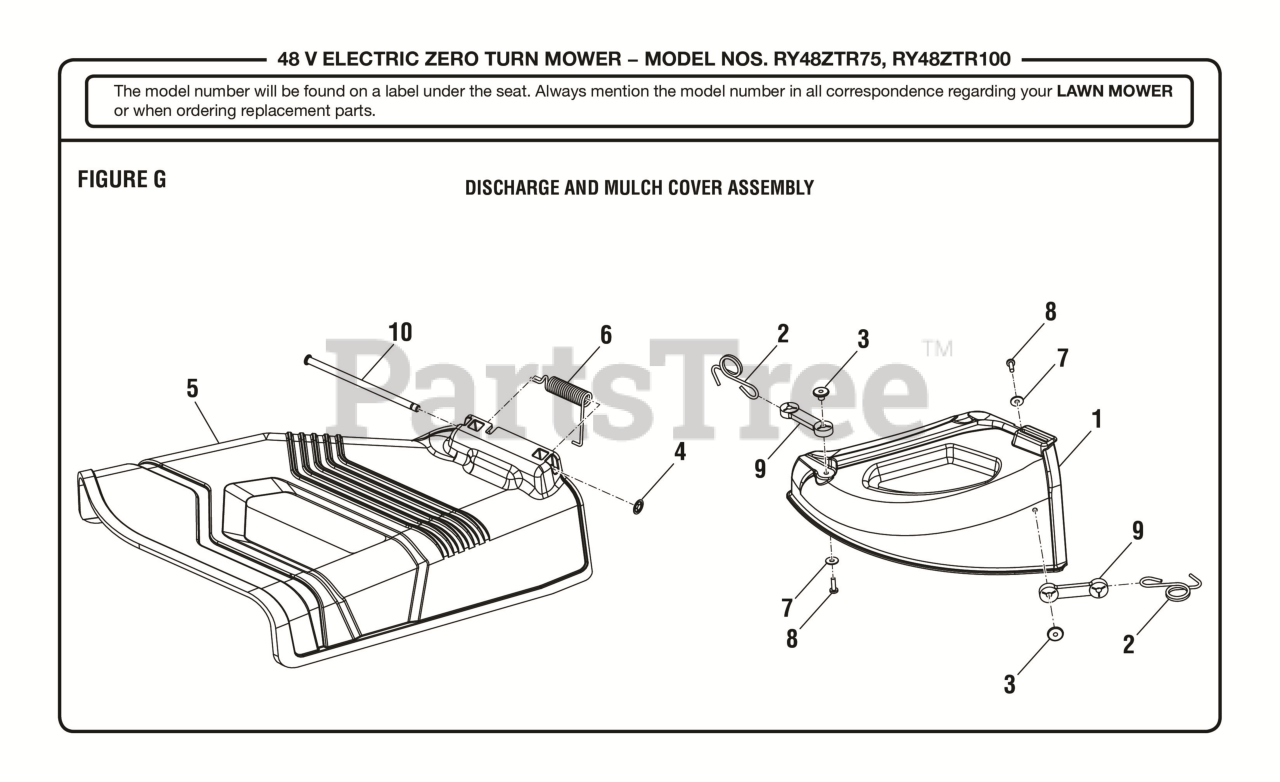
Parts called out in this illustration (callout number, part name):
1	Mulch Plug, ZTR
2	SPRING, LATCH
3	ANCHOR, BUNGIE, RIDING MOWER
4	Retainer Clip
5	Side Discharge Chute, 42 in. Deck
6	Torsion Spring (19 x 62 x 3.02t)
7	WASHER, FLAT, 5.3 X 15 X 1, STEEL,
8	SCREW,PPHMS, M5 X 0.8 X 16 - STEEL,
9	RUBBER STRAP, MULCHING COVER
10	Hinge Pin (7.85 x 175.85)
